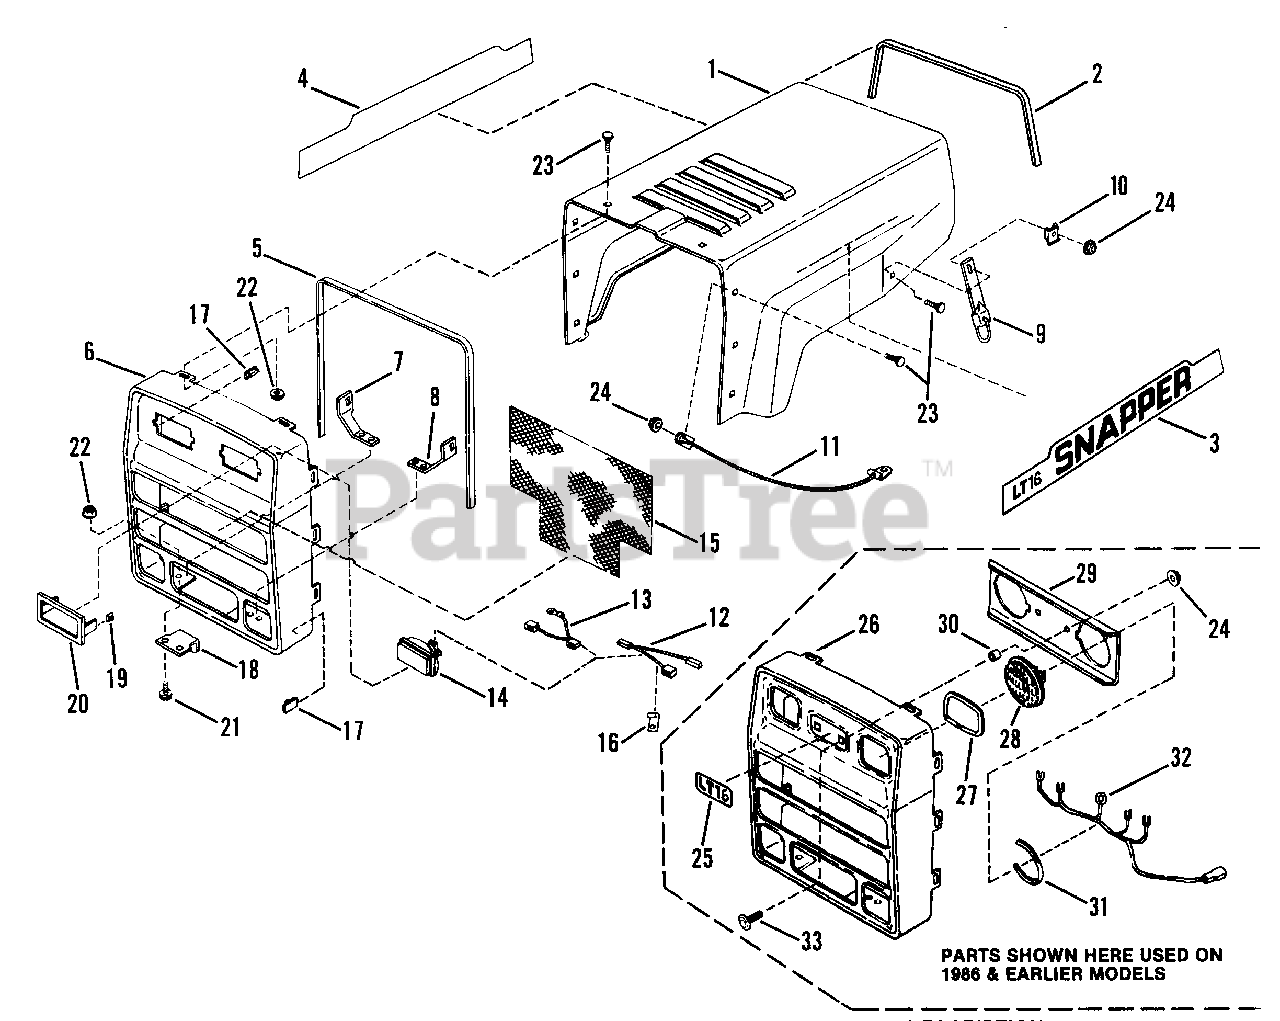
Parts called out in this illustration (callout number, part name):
1	HOOD, LT Series Tractor
2	TRIM, Hood
3	DECAL, Snapper, LT 16, L.H.
4	DECAL, Snapper, LT 16, R.H.
5	GASKET, Grill
6	GRILL
7	BRACE, Grill, R.H.
8	BRACE, Grill, L.H.
9	LATCH, Hood Retaining
10	CLIP, Hood Retainer
11	CABLE, Hood Stop, 16.5"
12	HARNESS, Head Lamp Wiring
13	HARNESS, Head Lamp Ground
14	HEAD LAMP
15	MESH, Grill
16	CLIP, Wiring Harness
17	CLIP
18	HINGE, Hood
19	CLIP, Head Lamp Mounting (Use 7017591 Wire Retainer & 7033211)
20	BEZEL, Head Lamp Mount (Use 7033211 & 7017591)
21	BOLT, 1/4-20 x 5/8" Hex Flange Lock, Grade 5
22	NUT, 1/4-20 Hex Flange Lock
23	BOLT, 1/4-20 x 5/8" Flat Head Carriage
24	NUT, 1/4-20 Hex Fl. Top Lock
25	DECAL, LT 12
25	DECAL, LT 16
26	GRILL (No longer available)
27	GASKET, Head Lamp
28	HEAD LAMP
29	BRACKET, Head Lamp
31	GASKET, Head Lamp to Bracket
32	HARNESS, Head Lamp Wiring
33	BOLT, 1/4-20 x Flat Head Carriage
